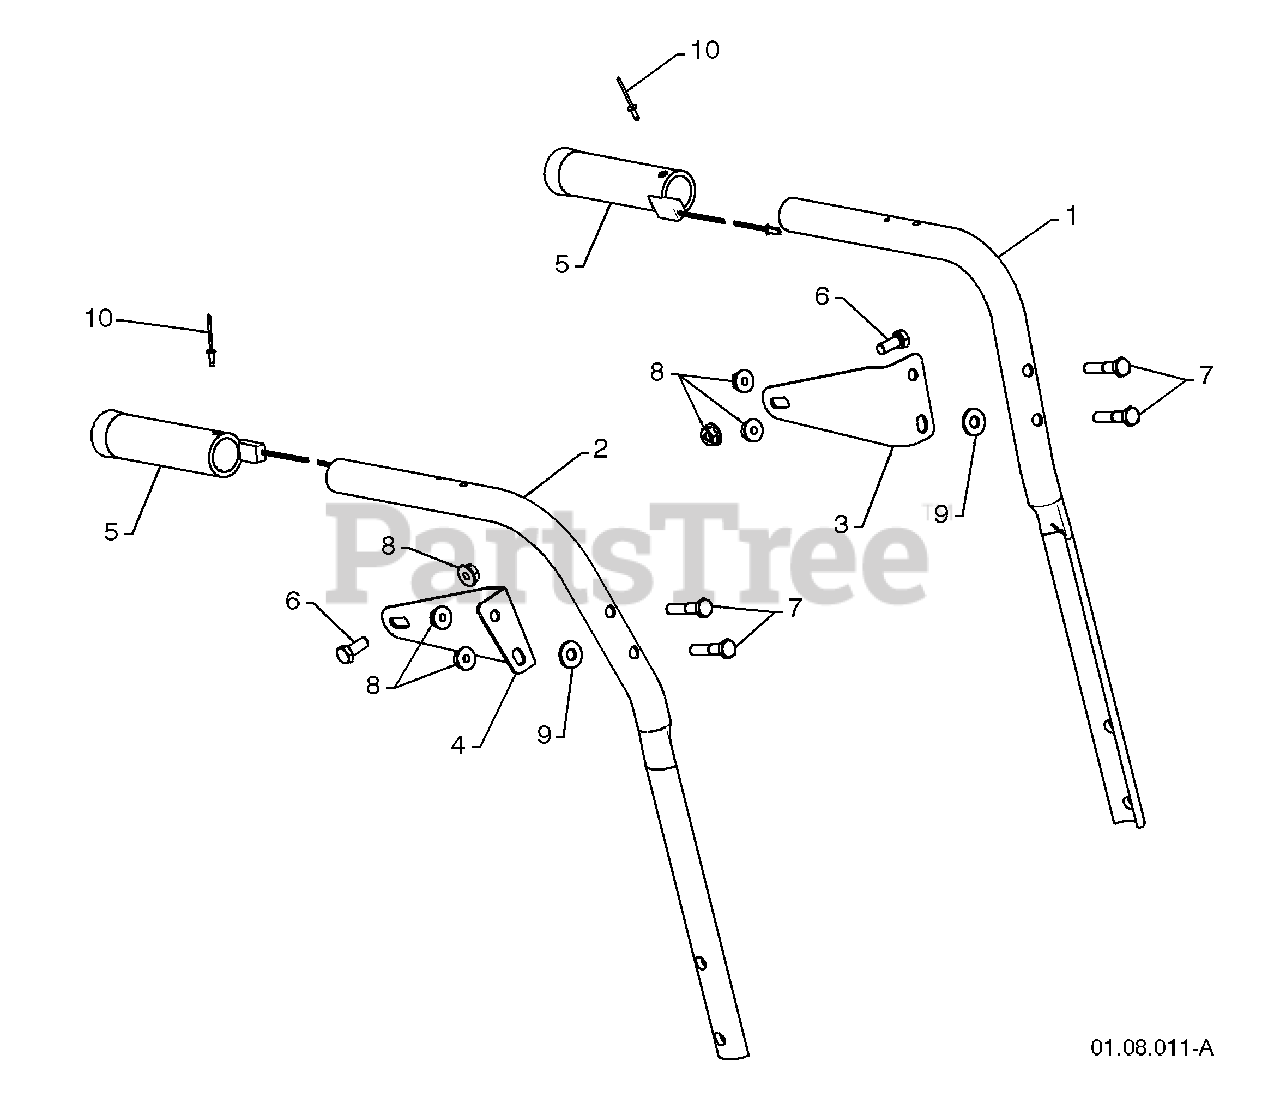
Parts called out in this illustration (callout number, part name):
1	PLOW HANDLE LH
2	PLOW HANDLE RH
3	PANEL BRACKET LH
4	PANEL BRACKET RH
5	HEATED HANDLE GRIP
6	SCREW 5/16-18 X .750
7	SCREW 5/16-18 X 1.50
8	NUT 5/16-18
10	POP RIVET 1/8
